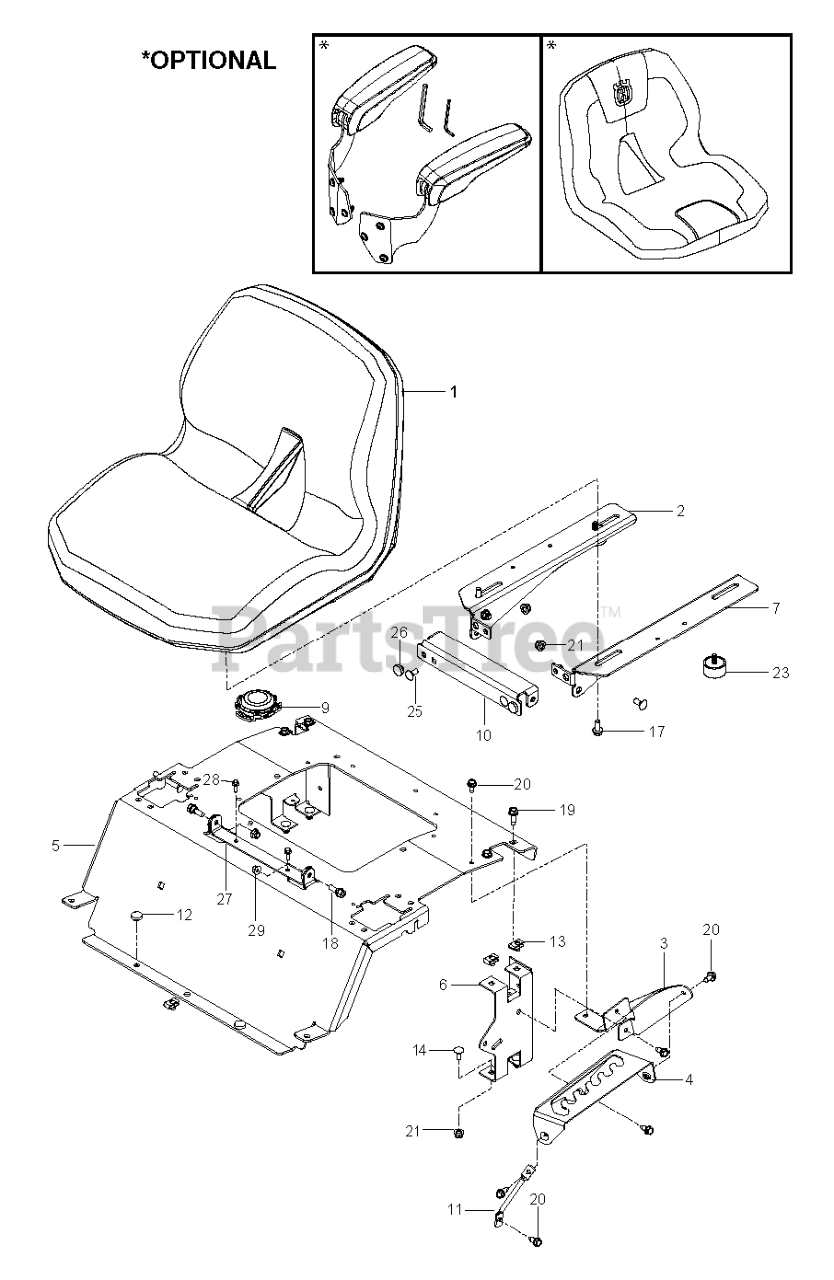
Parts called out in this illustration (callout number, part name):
2	BRACKET SEAT PAN RIGHT BLACK X
3	PLATE.SUPPORT.DECK.LIFT.X431
4	PLATE.DECK.LIFT.X431
5	PLATE.SUPPORT.SEAT.RZ.ORANGE
6	SUPPORT REAR SEAT BLACK
7	BRACKET SEAT PAN LEFT BLACK X4
9	SWITCH.SEAT.DP W/RAMPS
10	BRACKET FRONT SEAT PAN BLACK X
11	SUPPORT.LEG.DECK.LIFT
12	GROMMET.BUMPER
13	U-CLIP 5/16-18 NUT RETAINER
14	RP BOLT 5/16-18 X3/4 ZN/YEL GR
17	HHFS 5/16-18 X 3/4
18	BOLT, SHOULDER
19	HHFS 5/16-18 X 3/4
20	BOLT.5/16HEX.WHS.HD
21	5/16-18 NYLOC FLANGE NUT
23	BUMPER 5/16-18
25	BOLT 5/16C X 3/4" CARRIAGE
26	GROMMET, BUMPER
27	BRACKET.SEAT.REINF.X668
28	SCREW.FLG.LOCKING.1/4-20X.75
29	NUT T
